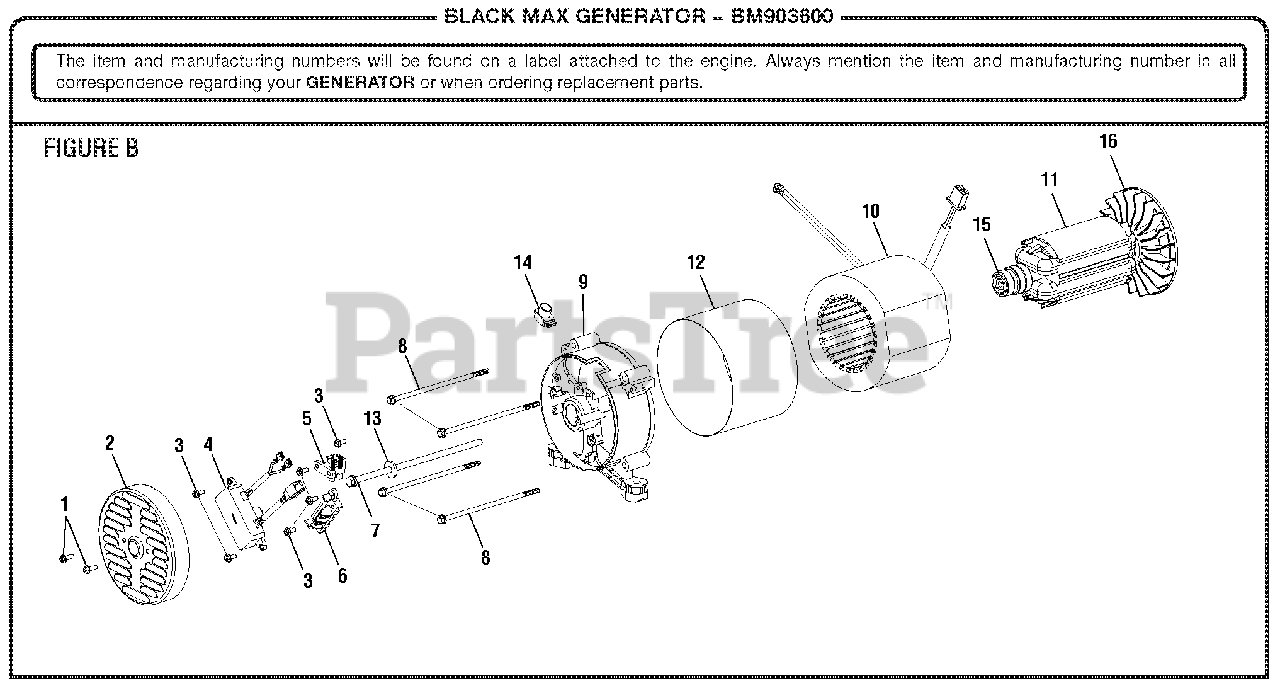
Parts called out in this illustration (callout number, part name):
1	Bolt (M5 x 12 mm, Hex Flange Hd.)
2	Brush Cover
3	Bolt (M5 x 16 mm, Hex Flange Hd.)
4	Automatic Voltage Regulator
5	Brush Assembly
6	Terminal Block
7	Rotor Bolt
8	Stator Bolt
9	Bearing Housing
10	Stator Assembly
11	Rotor Assembly
13	Rotor Washer
14	Rubber Boot
15	Ball Bearing
